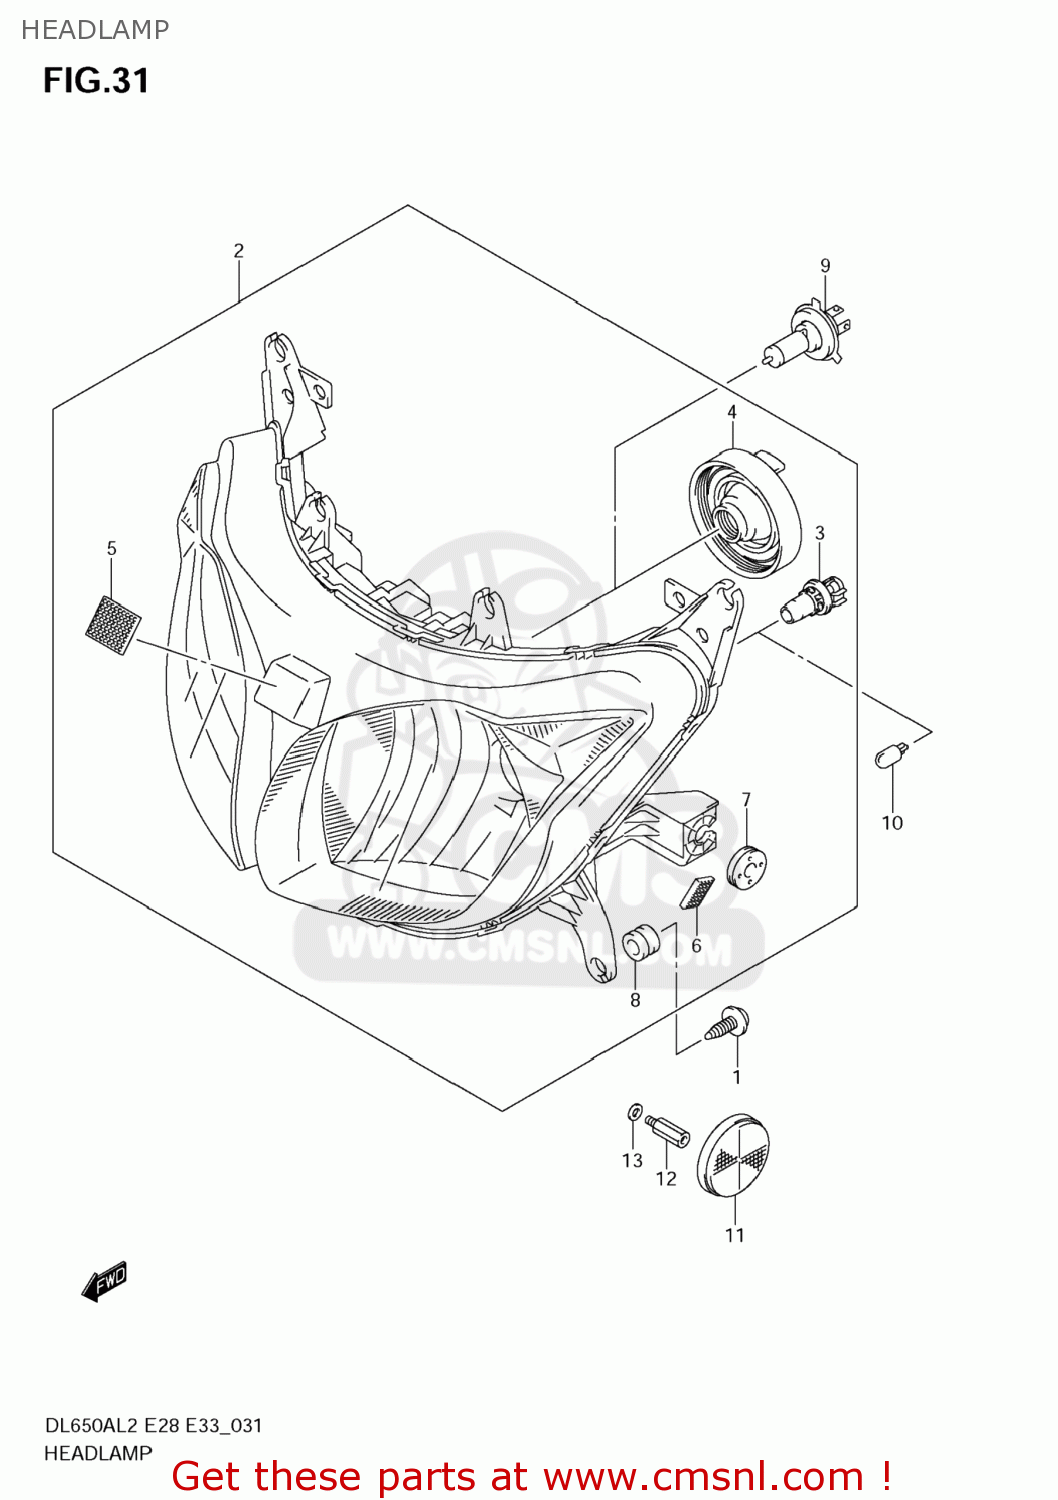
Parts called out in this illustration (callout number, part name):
1	SCREW(5X15)
2	HEADLAMP ASSY
3	SOCKET,POSITION LAMP
4	COVER,SOCKET
5	FASTENER
6	FASTENER,COWLING
7	CUSHION
8	CUSHION
9	BULB(12V60/55W,H4)
10	BULB(12V5W)
11	REFLEX REFLECTOR ASSY,FR SIDE
12	BOLT(5X10)
13	WASHER
